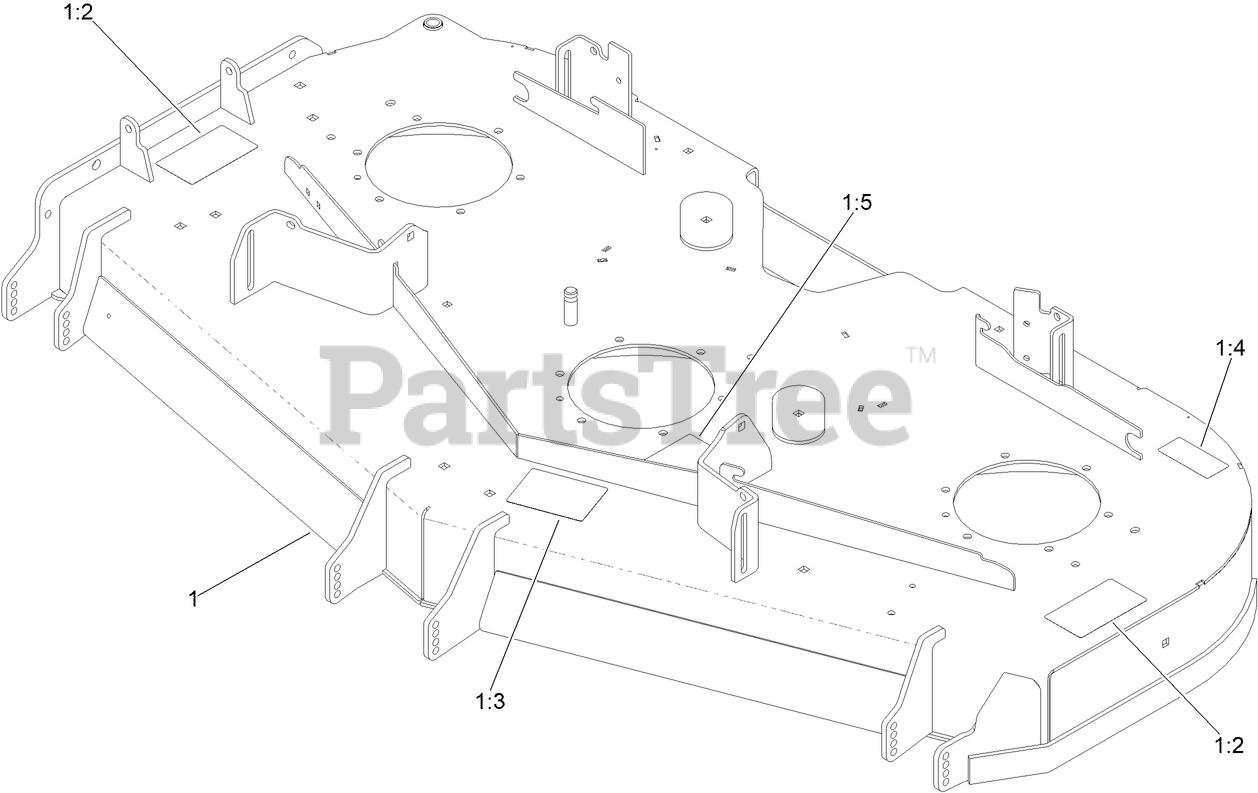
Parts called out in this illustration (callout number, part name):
1	Deck ASM W/Decals
1:2	DECAL-DANGER
1:3	DECAL-SCALP, ANTI
1:4	DECAL-BOLT TORQUE
1:5	DECAL-ROUTING, BELT
